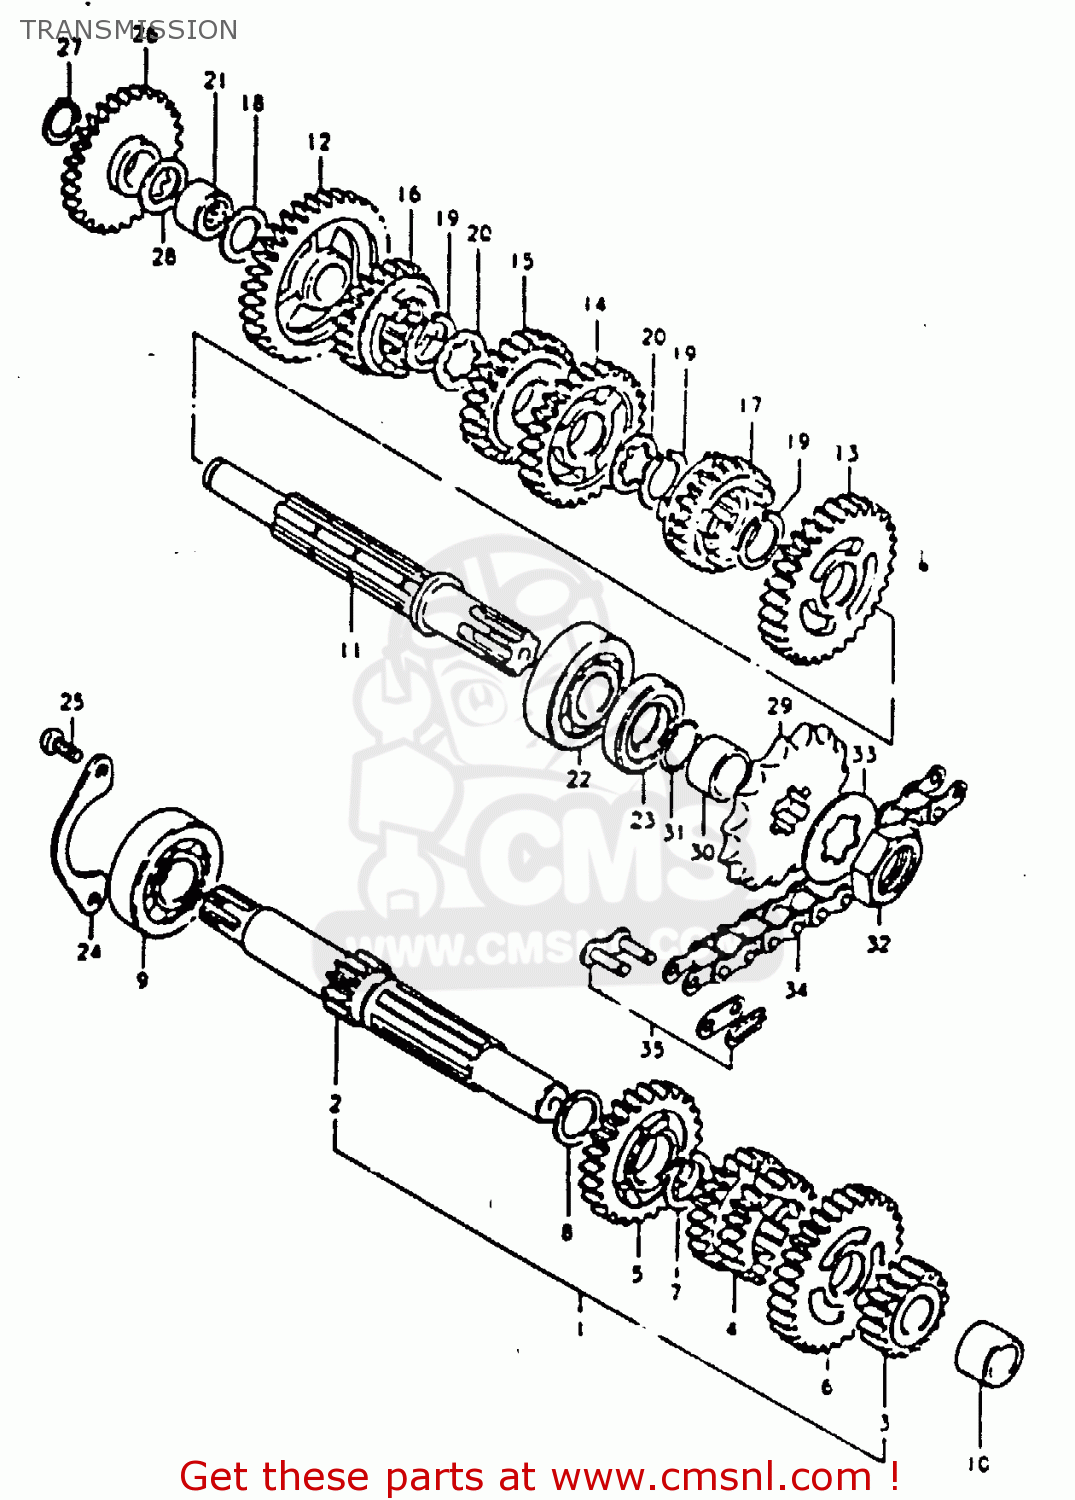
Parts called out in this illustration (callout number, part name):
1	SHAFT ASSEMBLY,COUNTER
2	SHAFT,COUNTER
3	GEAR,SECOND DRIVE
4	GEAR,THIRD/FOURTH DRIVE
5	GEAR,FIFTH DRIVE
6	GEAR,SIXTH DRIVE
7	CIRCLIP
8	WASHER
9	Bearing
10	BUSH(15X22X15)
11	SHAFT,GEAR SHIFT
12	GEAR,1ST DRIVEN
13	GEAR,SECOND DRIVEN
14	GEAR,THIRD DRIVEN
15	GEAR,FOURTH DRIVEN
16	GEAR,FIFTH DRIVEN
17	GEAR,SIXTH DRIVEN
18	WASHER,THRUST
19	CIRCLIP
20	WASHER,LOCK
21	BEARING(15X22X12)
22	Bearing
23	SEAL,OIL(25X40X7)
24	RETAINER,CNTR SHAFT BEARING
25	SCREW 6X12
26	GEAR,KICK STARTER IDLE
27	CIRCLIP,15MM
28	WASHER,THRUST
29	SPROCKET,ENGINE
30	SPACER(20X25X12.5)
31	O RING(D:1,ID:19.5)
32	NUT
33	WASHER,LOCK
34	CHAIN ASSEMBLY,DRIVE
35	JOINT ASSEMBLY,CHAIN
